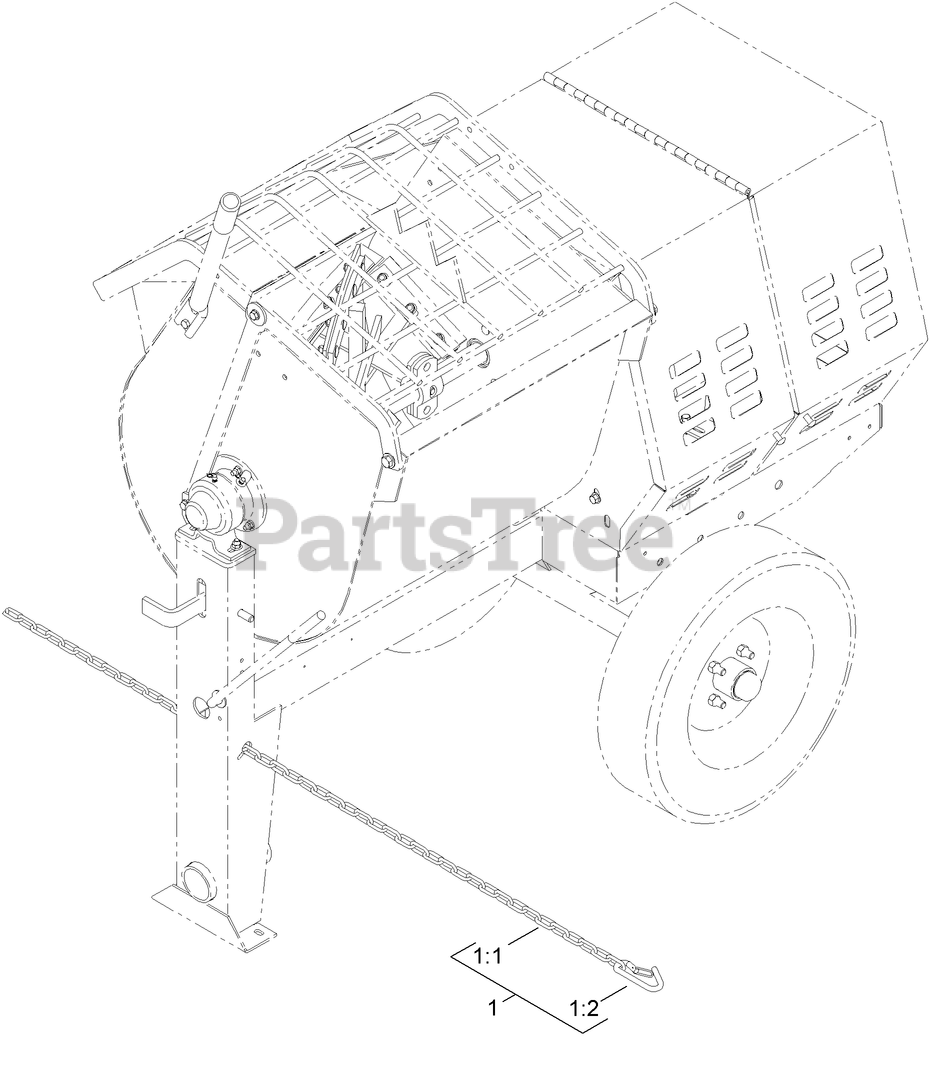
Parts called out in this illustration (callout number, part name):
1	SAFETY CHAIN KIT
1:1	CHAIN-144 INCH
1:2	HOOK-CHAIN, SAFETY LATCH
